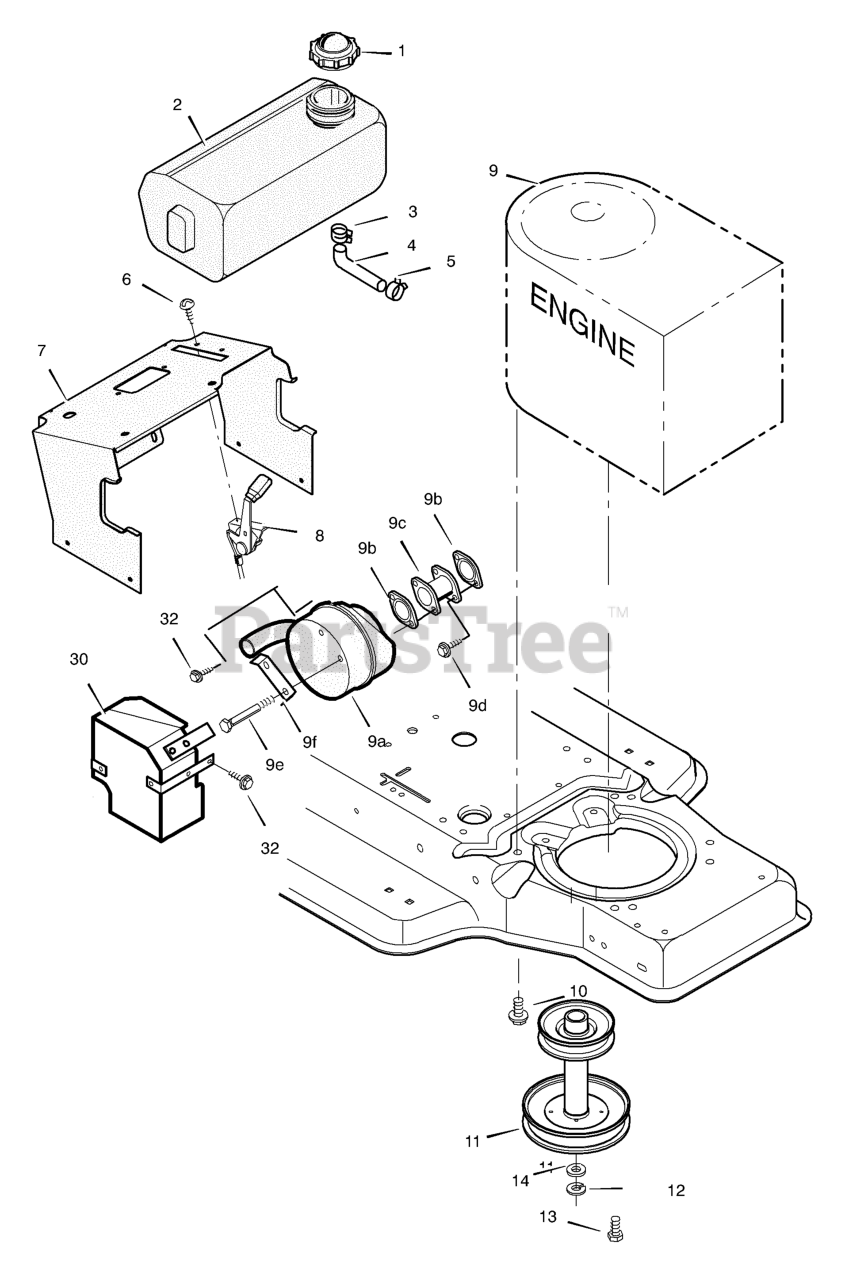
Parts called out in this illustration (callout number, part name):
1	Fuel Cap
2	Fuel Tank
3	Hose Clamp
4	Fuel Line (Must cut to length)
5	Hose Clamp
8	Throttle Control
9	Engine *
10	Bolt, Engine Mount
11	STACK PULLEY ASSEMBLY
12	Lockwasher
13	Bolt, Hex
30	Shield, Heat
